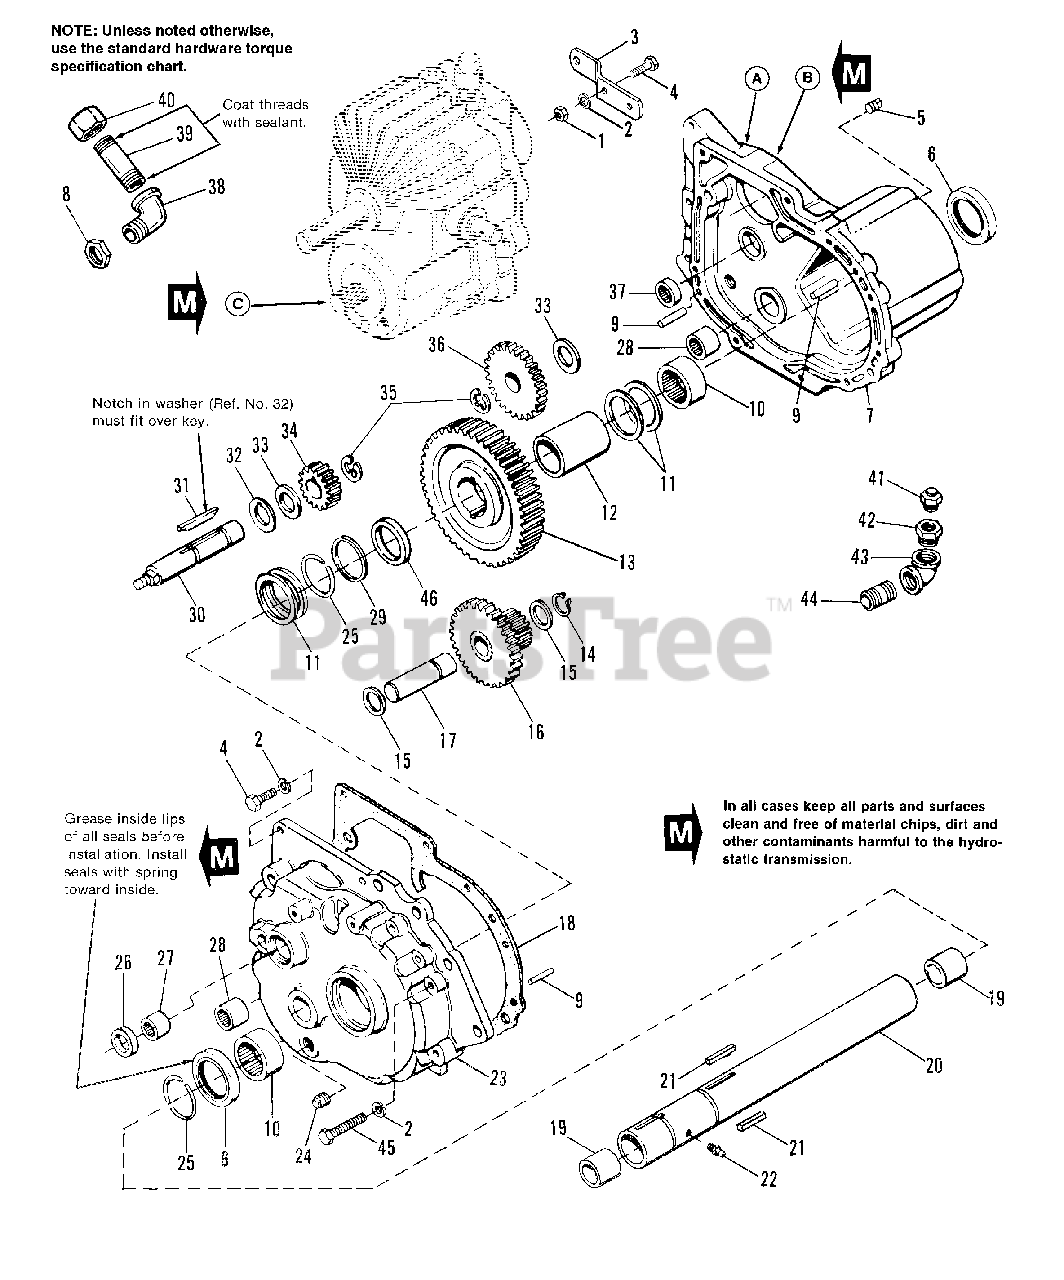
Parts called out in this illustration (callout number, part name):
1	NUT, Hex, Full, 5/16-18
2	LOCKWASHER, 5/16
3	SUPPORT, Spring
4	CAPSCREW, Hex Hd, 5/16-18 x 1
7	GEAR CASE ASSEMBLY,
8	LOCKNUT, 3/8, Rigid Conduit
9	PIN, Roll, 3/8 x 1
12	SPACER, Axle, L.H.
13	GEAR, Drive
14	RING, Retaining
16	PINION & SHAFT ASSEMBLY
17	SHAFT, Intermediate
20	TUBE ASSEMBLY, Axle
22	FITTING, Grease
23	COVER ASSEMBLY, Grease Case
25	RING, Retaining
28	BEARING, Needle
30	SHAFT, Brake
35	RING, Retaining
37	BEARING, Needle
38	ELBOW, Street
39	NIPPLE, Pipe
41	VALVE, Relief
42	BUSHING, Pipe
43	ELBOW, Pipe
44	NIPPLE, Pipe
45	CAPSCREW, Hex Head 5/16-18 x 2 G5
46	SPACER, Axle, R.H.
